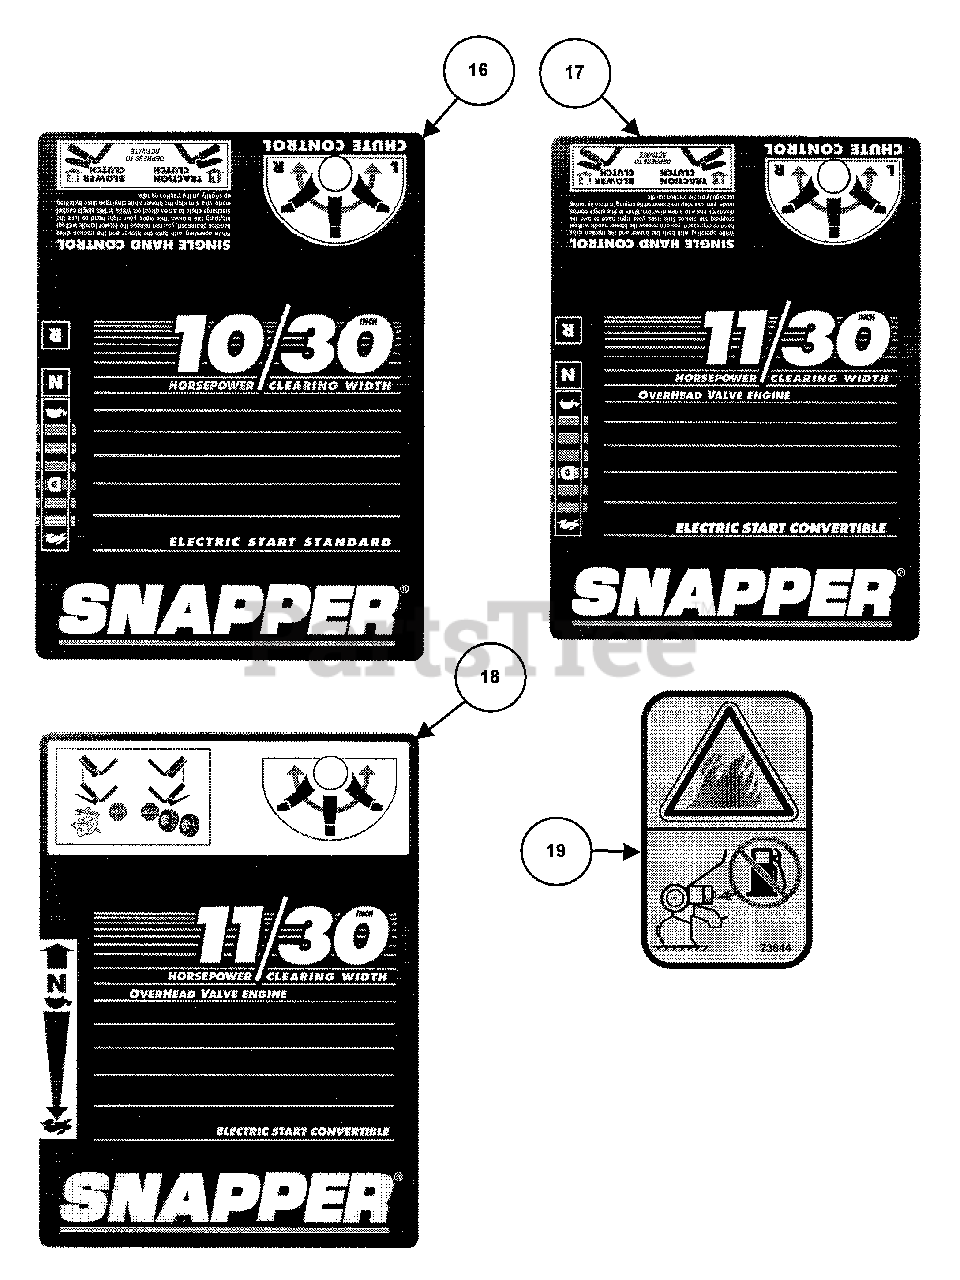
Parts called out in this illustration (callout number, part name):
16	DECAL, Control- 10/30
17	DECAL, Control- 11/30
18	DECAL, Control- E11/30
19	DECAL, Fuel Safety
